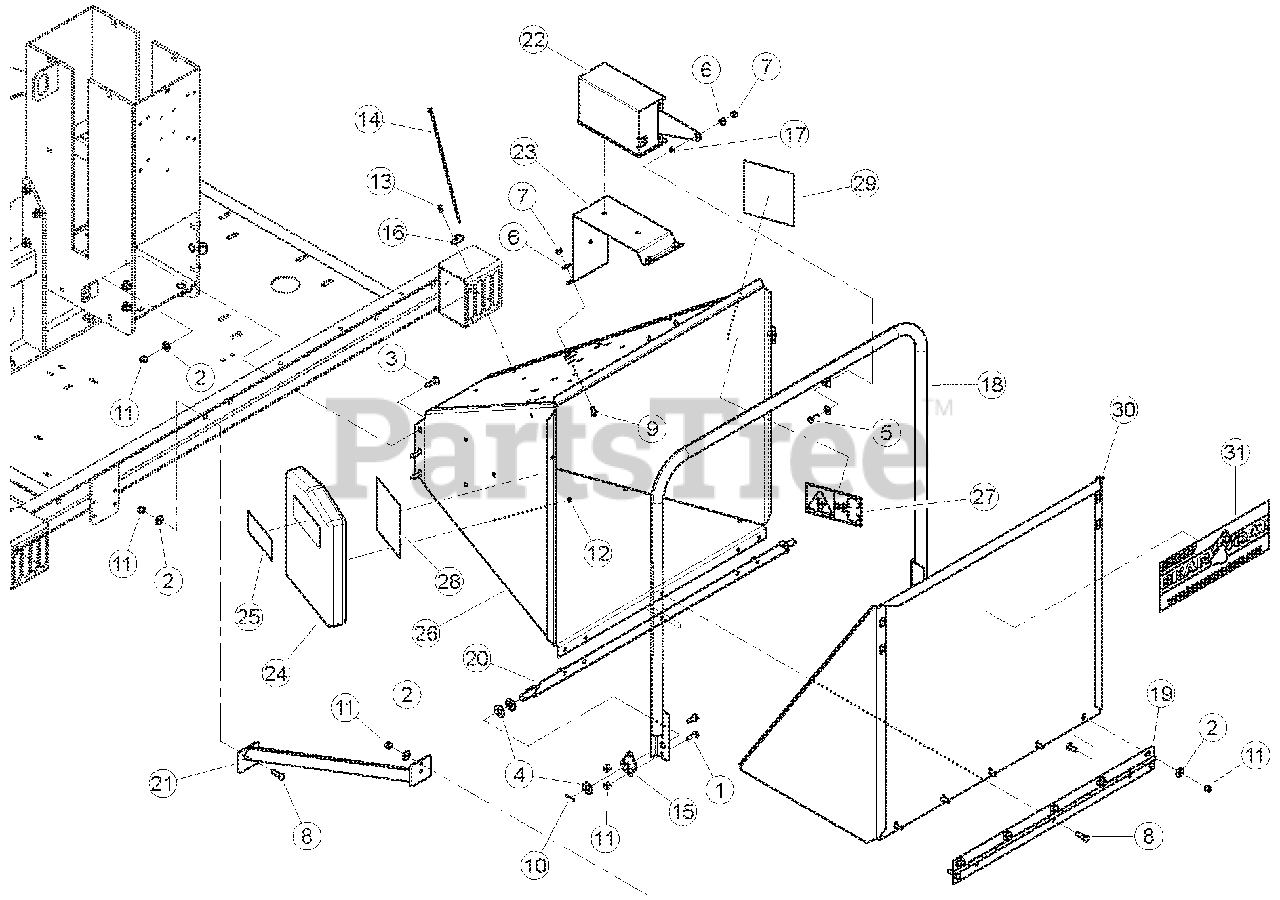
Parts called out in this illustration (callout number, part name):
1	BOLT, 3/8 X 1 HEX HD GR5 ZP
2	WASHER, 3/8 FLAT ZP
3	BOLT, 3/8 X 1-1/2 CRG GR5 ZP
4	WASHER, 5/8 SAE FLAT ZP
5	BOLT, 5/16 X 1 HHCS GR5 NC ZP
6	WASHER, 5/16 FLAT ZP
7	NUT, 5/16 NE NYLOCK ZP
8	BOLT, 3/8 X 1-1/4 HEX HD GR5 ZP
9	BOLT, 5/16 X 3/4 CRG GR5 NC ZP
10	PIN, 1/8 X 1.00 ZP COTTER
11	NUT, 3/8 NE NYLOCK ZP
12	RIVET, AL BLIND 1/4 X 1/2 DOME HEAD
13	RIVET, AL BLIND 1/4 X 3/4 DOME HEAD
14	STRAP, 11 IN. BLACK TIE
15	BEARING, SIDE FLNG MOUNT 5/8"
16	CLAMP, CABLE MOUNT
17	SPACER, IDLER PIVOT
18	WELDMENT, CONTROL ARM
19	HINGE, EXTENSION TRAY
20	WELDMENT, CONTROL PIVOT
21	WELDMENT, CHUTE SUPPORT
22	ASSEMBLY, SWITCH BOX
23	MOUNT, SWITCH BOX
24	ASSEMBLY, MANUAL CONTAINER SERVICE PART
25	DECAL, MUTILINGUAL MANUAL
26	ASSEMBLY, BIG CHIPPER CHUTE, SERVICE PART
27	DECAL, BLADE DANGER ISO
28	DECAL, FEED POSITION
29	DECAL, FEED POSITION
30	ASSEMBLY, CHUTE EXT. TRAY, SERVICE PART
31	DECAL, BEARCAT WEB
